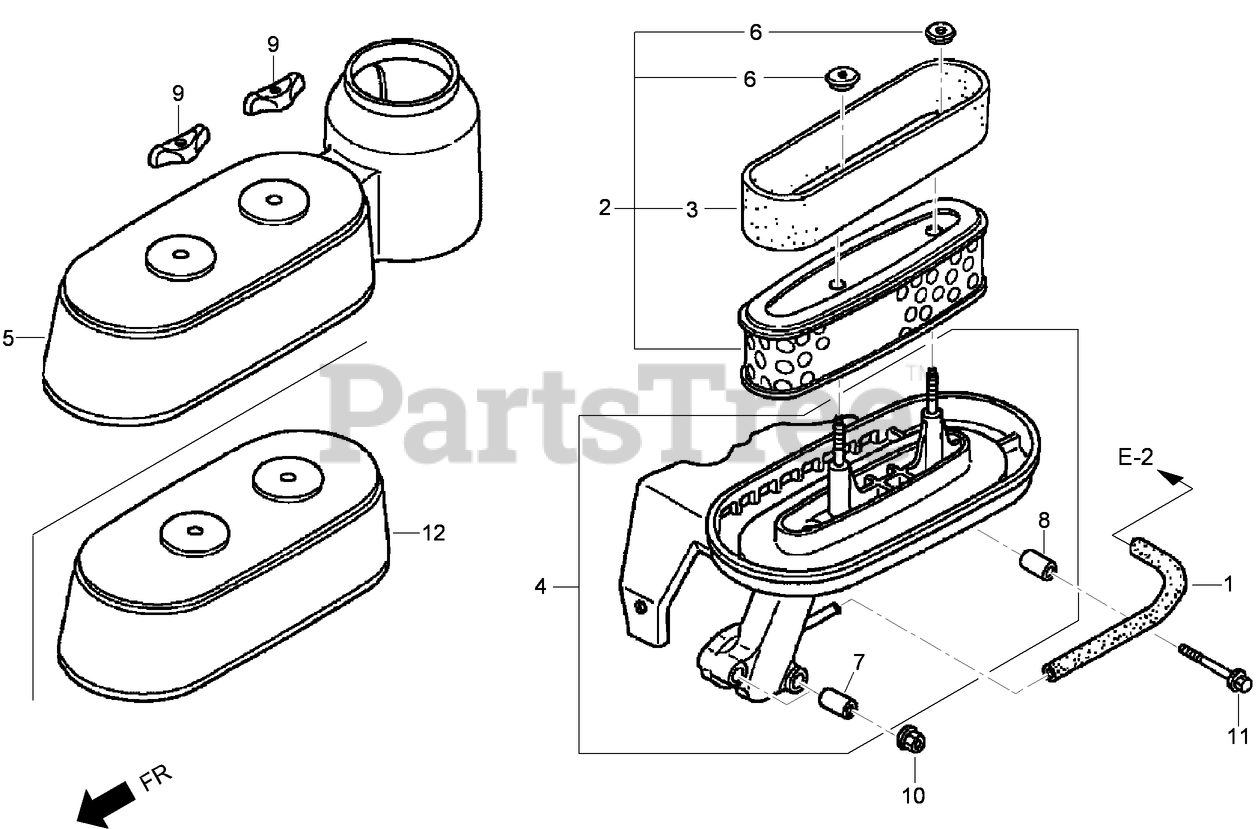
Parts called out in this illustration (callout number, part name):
1	Tube-Breather
2	ELEMENT-CLEANER, AIR
3	FILTER (OUTER)
4	HOUSING-CLEANER, AIR
5	COVER-CLEANER, AIR (Engine Serial No. Up To 1036455)
6	GROMMET-CLEANER, AIR
7	COLLAR-CLEANER, AIR
8	COLLAR B-CLEANER, AIR
9	NUT-CLEANER, AIR
10	NUT-FLANGE (6 mm)
11	BOLT-FLANGE (6X35)
12	COVER-CLEANER, AIR (Engine Serial No. From 1036456)
